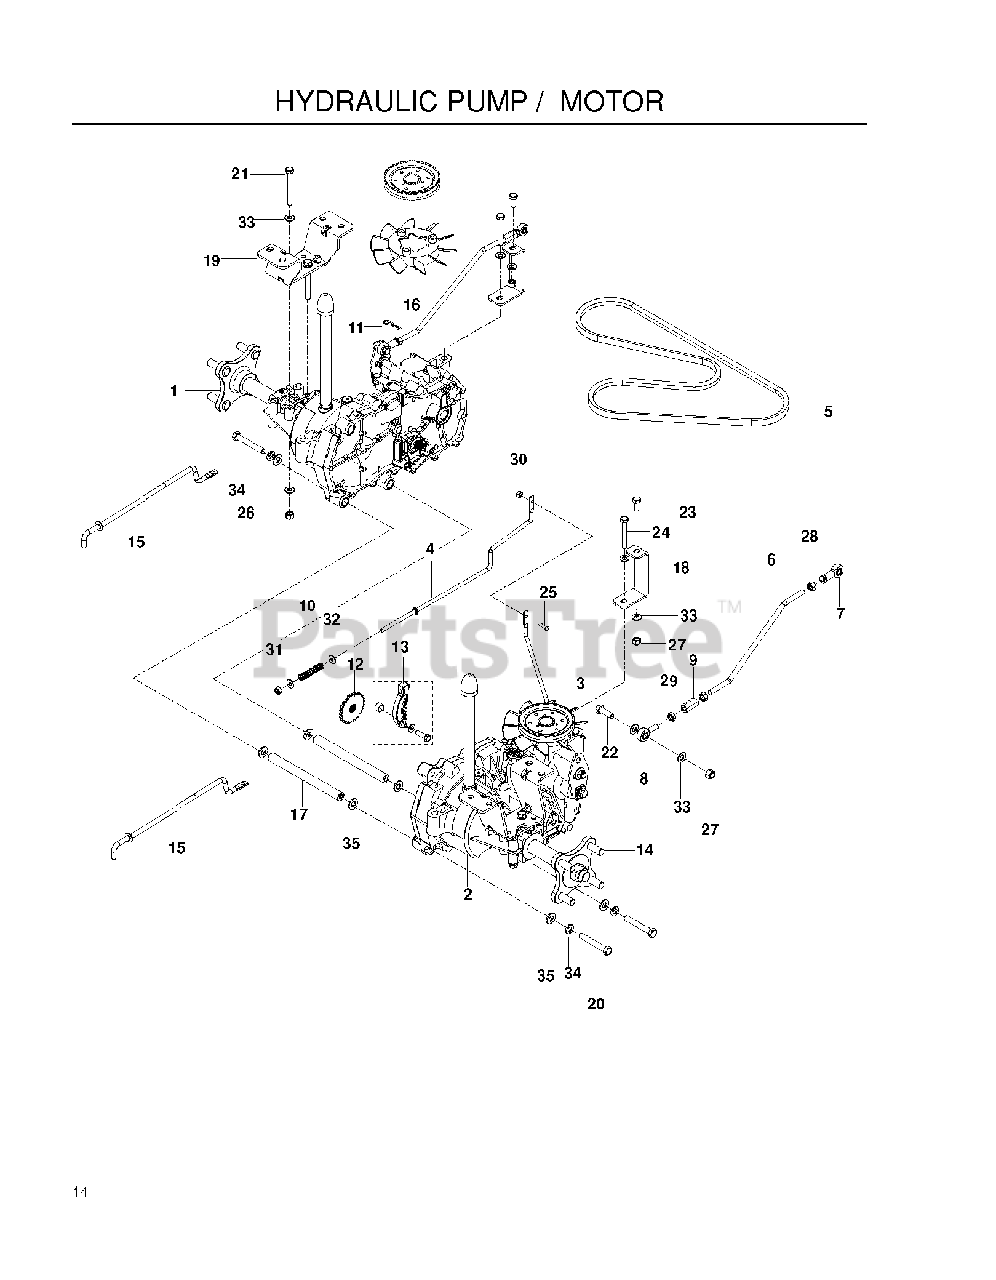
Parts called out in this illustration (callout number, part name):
1	HG_EZT, LT
2	HG_EZT, RT
3	LINKAGE.BRAKE.LT
4	LINKAGE, BRAKE RT
5	BELT, HYDRO PUMP
6	ROD, MOTION CONTROL
7	RH ROD END
8	RB ROD.END.LH
9	ROD END COUPLER
11	HAIRPIN #2
12	HG_DISC COG BRAKE 51635
13	HG_KIT BRAKE ARM (EZT)
14	HG_KIT, HYDRO-GEAR HUB
15	LINKAGE, BYPASS, EZT
16	HG_HYDRO FAN 51365
17	SPACER TUBE, EZT
18	SUPPORT.FRONT.TRANS.BLACK.
19	EZT MOUNT, REAR, BLACK
20	HCS 3/8C X 2 1/2
21	HCS 5/16C X 2-3/4
22	HCS 5/16C X 1
23	HCS 5/16C X 3/4
25	SCR #10-24 X 3/4
26	NUT 5/16 NYLOC
27	5/16-18 THIN PROF NY
29	NUT 5/16F LEFTHAND
30	NUT 10-24 NYLOC
31	RP_NUT 1/4-20 NYLOC
32	WASHER 1/4 SAE
33	FLAT WASHER 5/16 SAE
34	SLW 3/8 STD
35	WASHER 3/8 SAE FLAT
